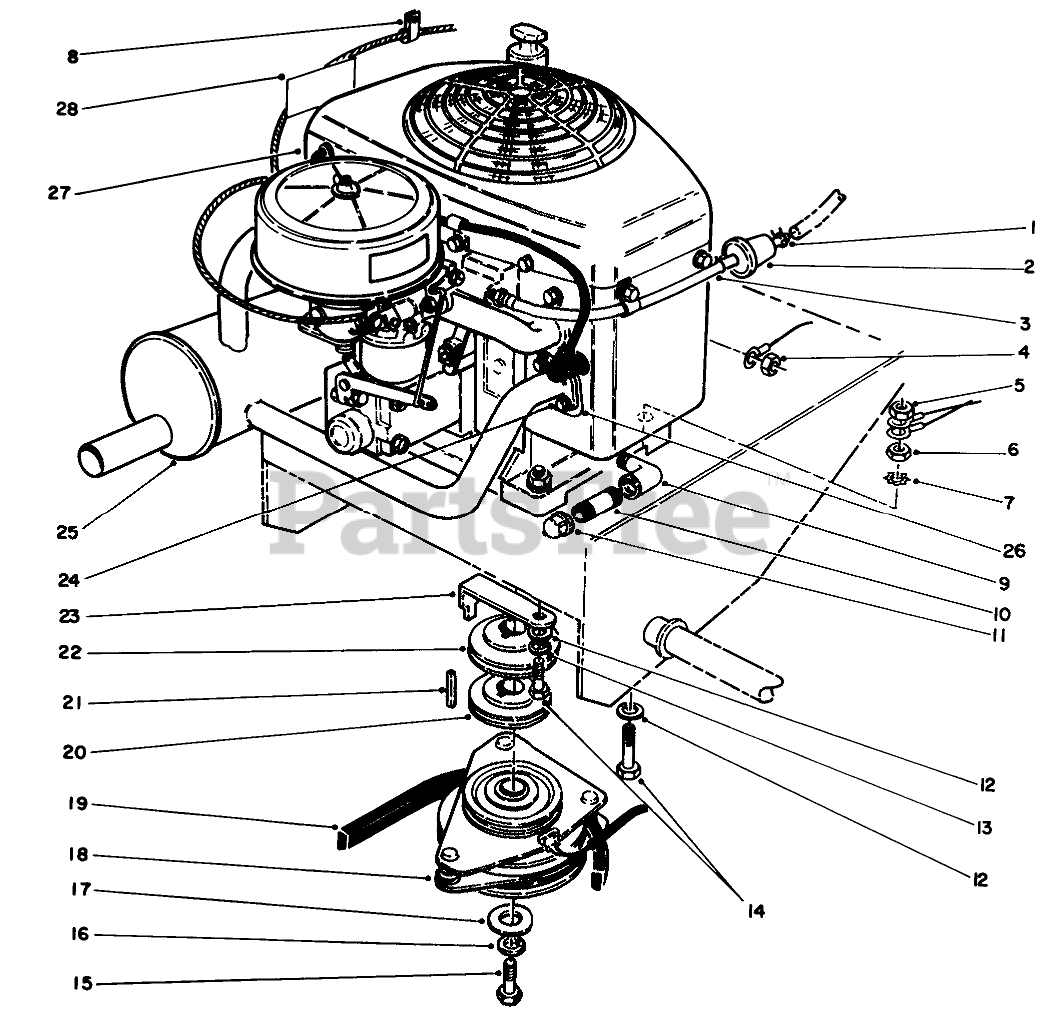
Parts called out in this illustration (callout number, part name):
1	CLAMP-HOSE
2	Fuel-Filter
3	Hose-Gas
4	NUT-KEPS
5	NUT-KEPS
6	NUT-LOCK, CONE
7	WASHER-LOCK
8	CLAMP-R
9	ELBOW-STREET, 90 DEG
10	NIPPLE
11	CAP-PIPE
12	WASHER-PLAIN
13	WASHER-LOCK
14	SCREW-HH
15	SCREW-HH
16	WASHER-LOCK
17	WASHER-CLUTCH
18	CLUTCH/BRAKE
19	V-BELT, DRIVE
20	SHEAVE-LOWER HALF
21	KEY-SQUARE
22	SHEAVE-UPPER HALF
23	Retainer-Clutch
24	SCREW-HSH
25	MUFFLER
26	EXHAUST GASKET F/W ENG.
28	DECAL-SURFACE, HOT
